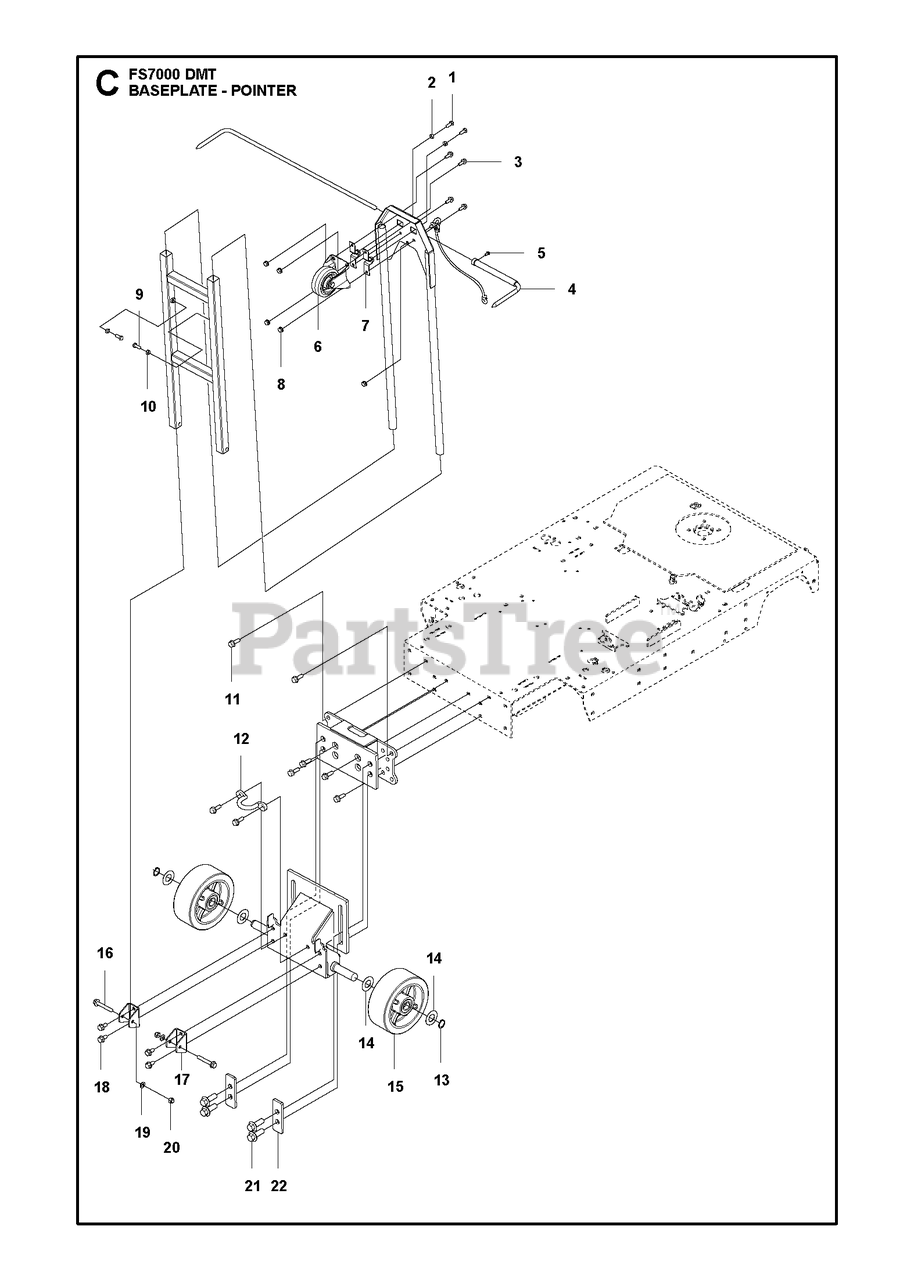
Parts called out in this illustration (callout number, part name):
2	HEXAGON NUT
5	SCREW EHHM
8	HEXAGON NUT FLANGE
10	HEXAGON NUT
13	CIRCLIP
19	WASHER
20	HEXAGON LOCKING NUT
